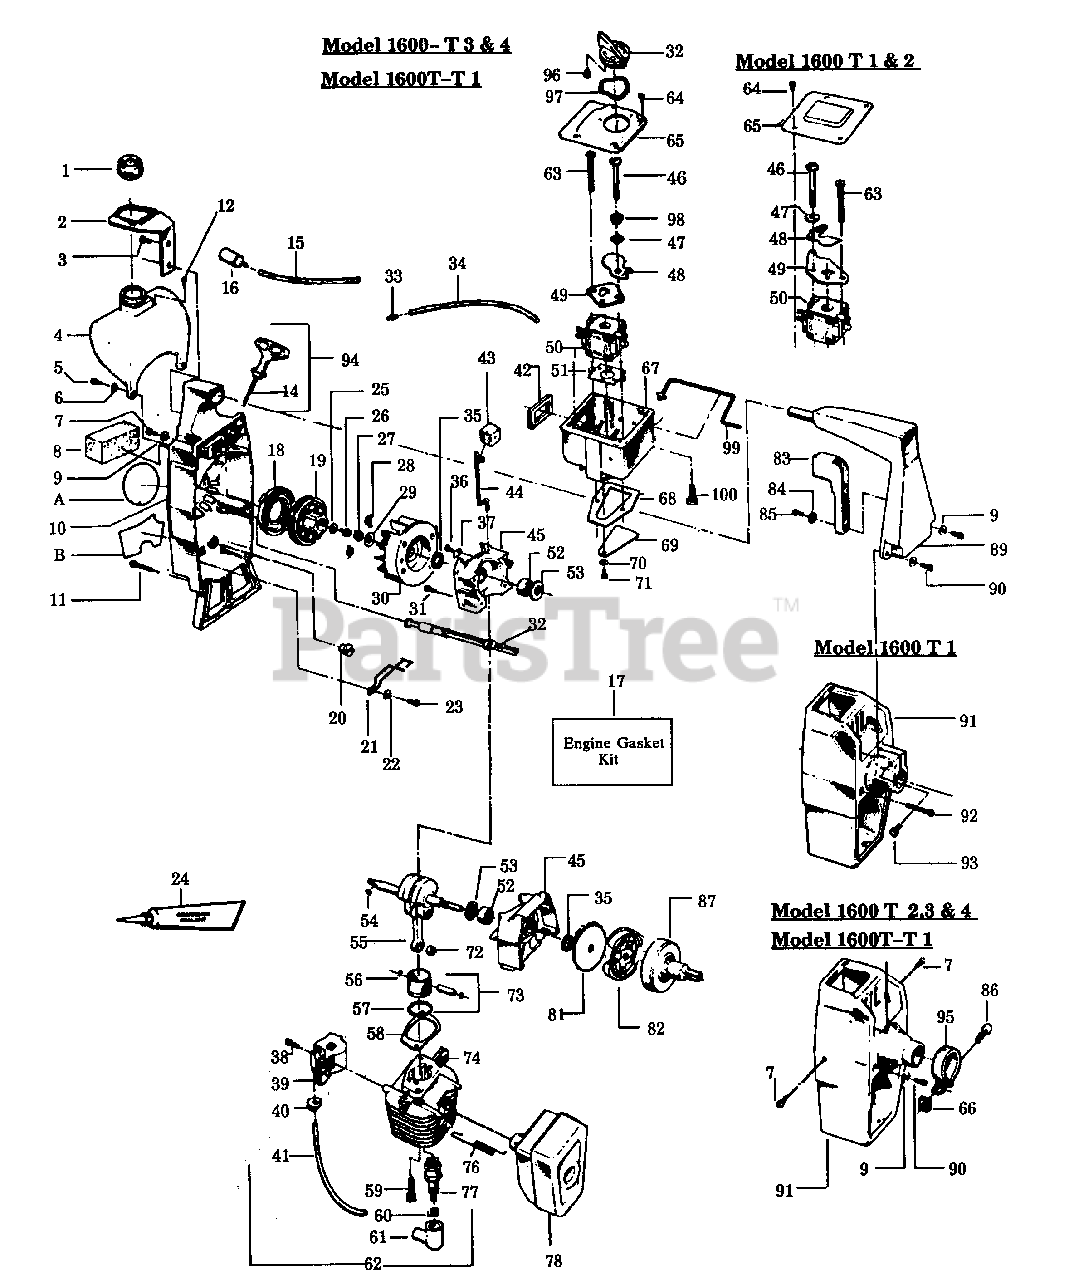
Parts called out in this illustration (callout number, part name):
1	Fuel Cap Ass'y.
2	Fuel Tank Bracket
3	Screw #1/4-20x1-1/8
4	Fuel Tank Ass'y. (Inc.1,12,15 & 16)
5	Screw #10x1
7	1600 G.TRIMMER-T1
7	1600 G.TRIMMER-T2,3 & 4; 1600T-T1
8	Air Filter
9	Washer #10-1600 G.TRIMMER-T1 Only
10	Fan Housing
11	1600 G.TRIMMER-T1
11	1600 G.TRIMMER-T2,3, & 4; 1600T-T1
12	Check Valve - Duck Bill
14	Rope Kit
15	Fuel Line-1600 G.TRIMMER-T1 & 2
15	Line Kit - 1600 G.TRIMMER-T 3 & 4; 1600T-T1
16	1600 G.TRIMMER-T1 & 2
16	1600 G.TRIMMER-T 3 & 4; 1600T-T1
17	Engine Gasket Kit (*Indicates Contents)
18	Starter Recoil Spring
19	Starter Pulley
20	Kill Switch Button
21	Kill Switch Spring
23	Screw #8x3/8
24	Crankcase Sealant - 3 oz. tube
25	Washer #10
26	Screw #10-3/4
27	Flywheel Nut
28	Starter Dog Spring
30	Flywheel Ass'y. (Inc.28)
32	1600 G.TRIMMER-T1 & 2
32	1600 G.TRIMMER-T3 & 4; 1600T-T1
33	1600 G.TRIMMER-T1 & 2
33	1600 G.TRIMMER-T3 & 4; 1600T-T1
34	Carburetor Fuel Line
35	Crankshaft Seal
36	Screw - 1600 G.TRIMMER-T1 & 2 Only
37	Choke Wire Clamp - 1600 G.TRIMMER-T1 & 2
38	Screw #8-32x3/4
39	Ignition Module Kit
40	Plug Wire Grommet
41	High Tension Lead Wire
42	Carburetor Case Seal
43	Choke Wire Boot - 1600 G.TRIMMER-T1 & 2 Only
44	Choke Wire - 1600 G.TRIMMER-T1 & 2 Only
45	Crankcase Ass'y (Inc.35,52 and Qty. 1 of #31)
46	1600 G.TRIMMER-T1 & 2
46	1600 G.TRIMMER-T3 & 4; 1600T-T1
47	Wave Washer
48	1600 G.TRIMMER-T1 & 2
48	1600 G.TRIMMER-T3 & 4; 1600T-T1
49	1600 G.TRIMMER-T1 & 2
49	1600 G.TRIMMER-T3 & 4; 1600T-T1
50	Carburetor (WA-149)
51	Carburetor Gasket
52	Crankshaft Bearing
53	Crankshaft Thrust Washer
54	Flywheel Key
55	1600 G.TRIMMER-T1 & 2
55	1600 G.TRIMMER-T3
55	1600 G.TRIMMER-T4; 1600T-T1
56	Wrist Pin Retainer
57	1600 G.TRIMMER-T1,2 & 3
57	1600 G.TRIMMER-T4; 1600T-T1
58	Cylinder Gasket
59	Screw #1/4-20x3/4
60	Spark Plug Connector
61	Spark Plug Boot
62	High Tension Lead Ass'y.(Inc.41,60,61)
63	1600 G.TRIMMER-T1 & 2
63	1600 G.TRIMMER-T3 & 4; 1600T-T1
65	1600 G.TRIMMER-T1 & 2
65	1600 G.TRIMMER-T3 & 4; 1600T-T1
66	Nut #12-24
67	1600 G.TRIMMER-T1 & 2
67	1600 G.TRIMMER-T3 & 4;1600T-T1
68	Carburetor Case Crankcase Gasket
69	Reed Valve
70	Reed Valve Washer
71	Screw #6-19x5/16
72	1600 G.TRIMMER-T1, 2 & 3
72	1600 G.TRIMMER-T4; 1600T-T1
73	1600 G.TRIMMER-T1,2 & 3
73	1600 G.TRIMMER-T4; 1600T-T1
74	Cylinder
76	Muffler Attachment Spring
77	Spark Plug (CJ-14)
81	Clutch Washer Kit
82	Clutch Ass'y. Kit
83	Throttle Trigger
84	Throttle Washer
85	Screw #8-16x3/8
86	Screw 1/4-20x9/16 - 1600 G.TRIMMER-T2,3 & 4; 1600T-T1
87	1600 G.TRIMMER-T1
87	1600 G.TRIMMER-T2,3 & 4; 1600T-T1
90	Screw #10-24x7/8
91	1600 G.TRIMMER-T1
91	1600 G.TRIMMER-T2,3 & 4; 1600T-T1
92	Screw #10-24x1-1/2 - 1600 G.TRIMMER-T1 Only
93	Pinch Clamp Bolt-1600 G.TRIMMER-T1 Only
95	Clamp-1600 G.TRIMMER-Type 2,3 & 4 1600T-T1
97	Washer-1600 G.TRIMMER-T 3 & 4;1600T-T1
98	Spacer-1600 G.TRIMMER-T 3 & 4; 1600T-T 1
99	Throttle Wire-1600 G.TRIMMER-T3,4; 1600T-T1
100	Screw-1600 G.TRIMMER-T3 & 4; 1600T-T1
A	1600 G.TRIMMER-T1 & 2
A	1600 G.TRIMMER-T3 & 4; 1600T-T1
B	1600 G.TRIMMER-T1 & 2
B	1600 G.TRIMMER-T3 & 4;1600T-T1
